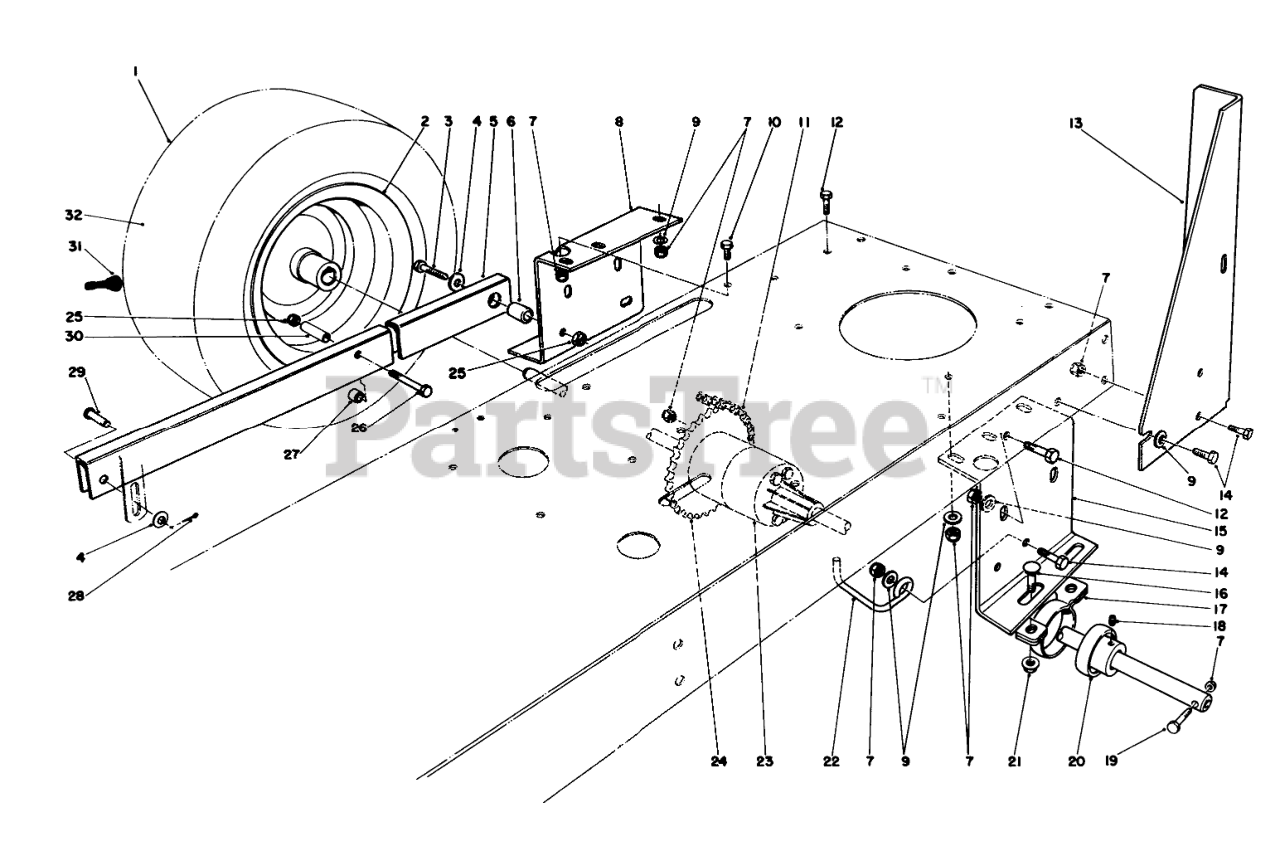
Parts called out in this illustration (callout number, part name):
3	SCREW-HH
4	WASHER-FLAT
5	REAR SUSP ARMR
6	PIN-SUPT ARM
7	NUT-LOCK, NI
8	RH REAR AXLE SUPT R
9	WASHER-PLAIN
10	SCREW-HH
11	ROLLER CHAIN
12	Screw
13	LH STANDBAR B
14	SCREW-HH
15	LH REAR AXLE SUPT R
16	SCREW-CARR
17	RTNR-PILLOW BLK
18	SCREW-SET, HSH
19	SCREW-HH
20	Bearing-Self Aligning (Incl. Ref. #18)
21	NUT-HF
22	BELT GUIDE
23	DIFFERENTIAL
24	42T DIFF SPROCKET
25	NUT-LOCK, CONE
26	SCREW-HH
27	INNER TUBE SPACER
28	PIN-COTTER
29	PIN-CLEVIS
30	OUTER TUBE SPACER
31	STEM-VALVE
32	TUBE-INNER
